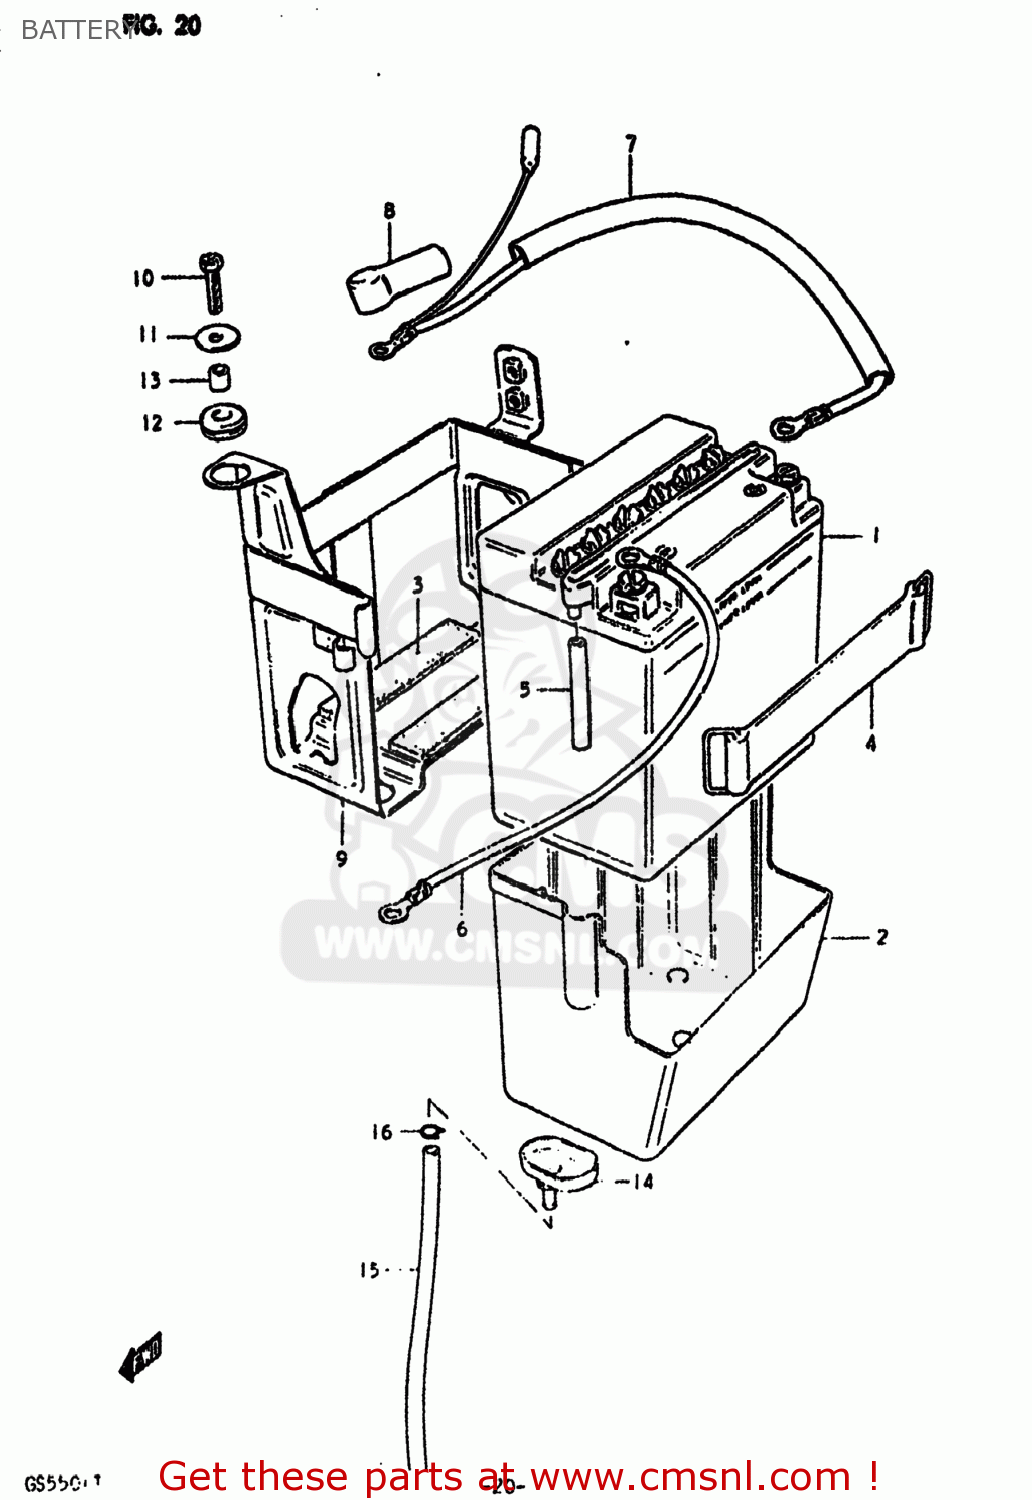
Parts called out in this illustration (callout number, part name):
1	BATTERY ASSY (12V)
2	CASE,BATTERY
3	PROTECTOR,20X9
4	BAND
5	HOSE, EXHAUST (L:45)
6	WIRE,STARTER MOTOR LEAD
7	WIRE,BATTERY PLUS
8	CAP,TERMINAL
9	HOLDER,BATTERY
10	BOLT(6X20)
11	WASHER
12	CUSHION
13	SPACER(6.1X9X7.5)
14	FUNNEL,BATTERY EXHAUST
15	HOSE,BATTERY EXHAUST
16	CLIP
